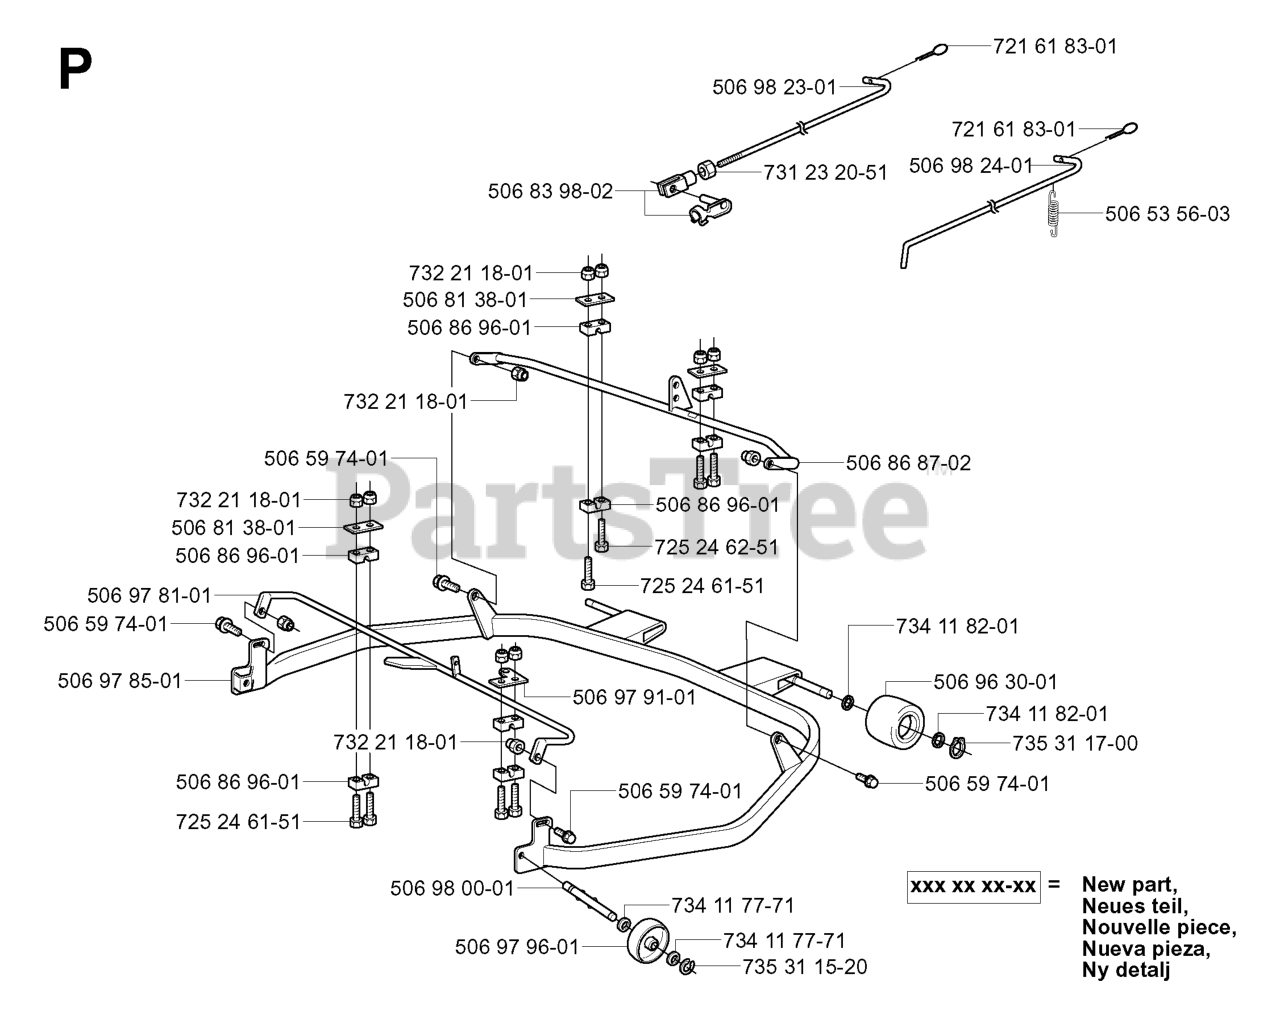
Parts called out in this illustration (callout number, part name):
650	SHAFT, AXLE 5/21 SC
651	SPACER, SLEV .407X.63X.440
652	WASHER, FLAT .406X .81X.
660	TIRE & RIM 8 X 1.75
661	WASHER, FLAT .406X .81X.
662	RETAINING RING
